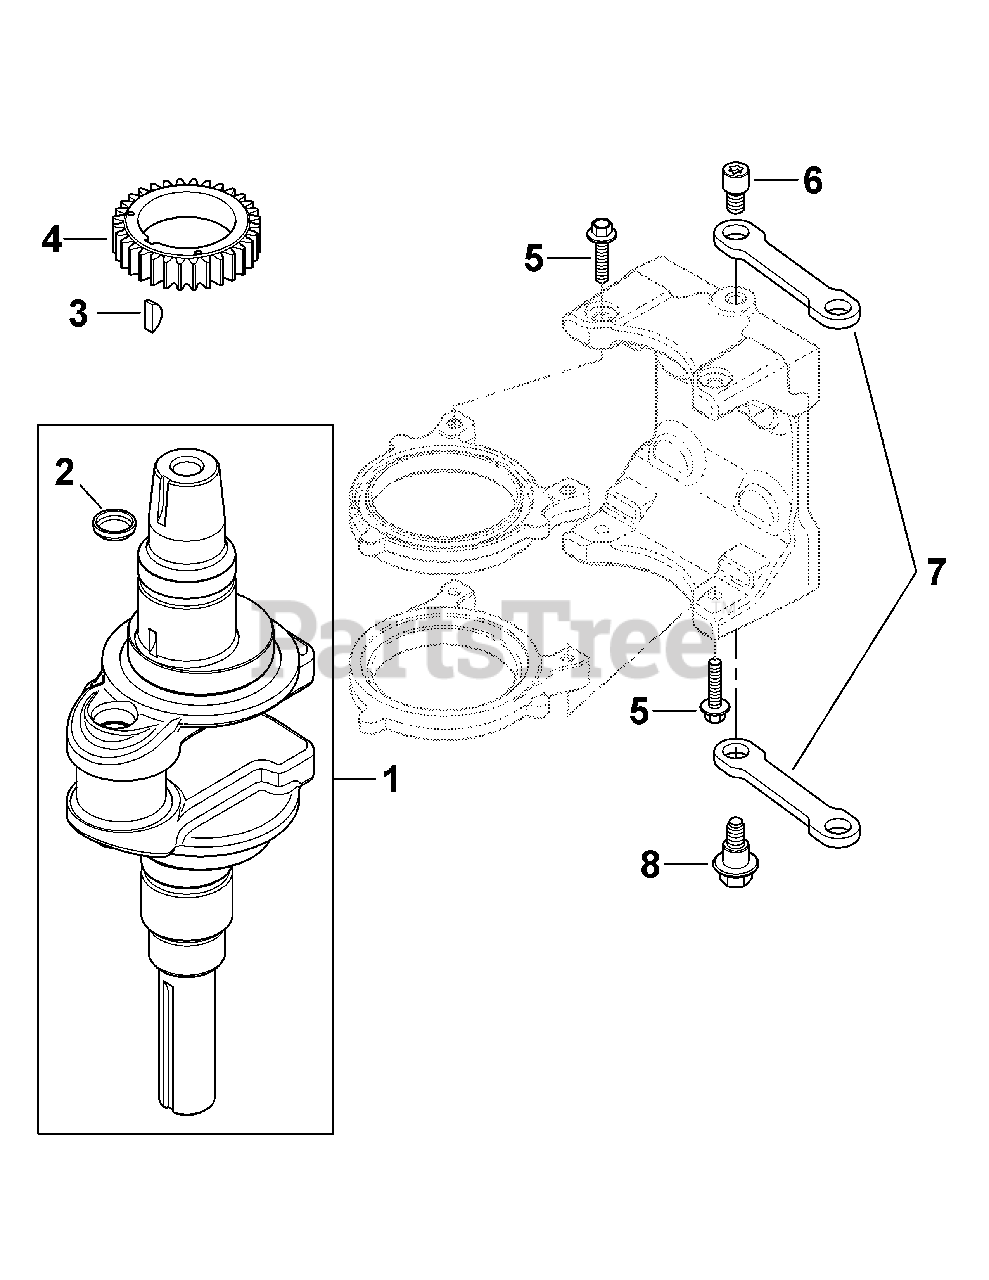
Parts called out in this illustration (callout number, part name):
1	Crankshaft Assembly Kit
3	Key, 3.16 X 5.8
4	Crankshaft Gear
5	Flange Screw, M6 X 1.0 X 25
6	Link Pivot Screw
7	Balance Weight Linkage
8	Shoulder Screw
